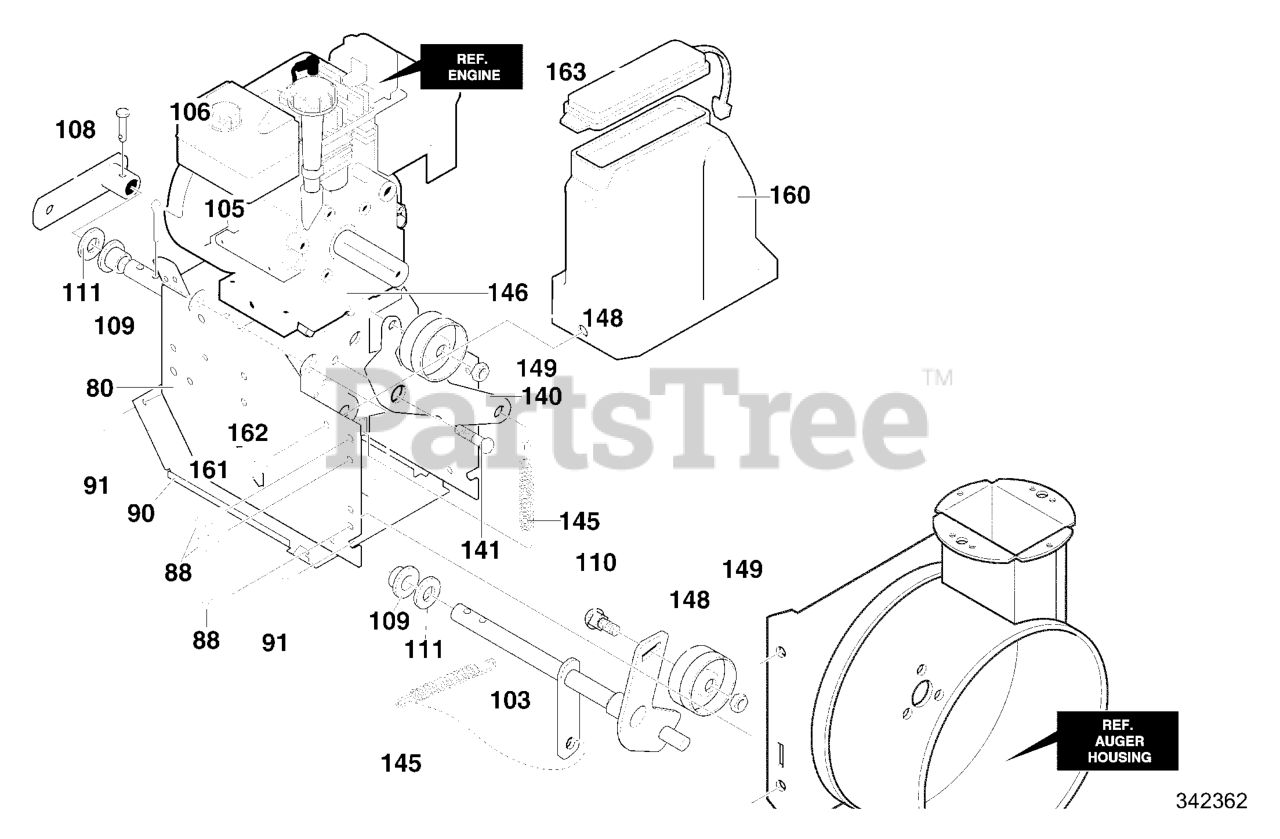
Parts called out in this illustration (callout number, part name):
80	FRAME ASSY
88	SCREW, 5/16-18 x 0.50
90	COVER, BOTTOM
91	SCREW, 1/4-20X .63
103	IDLER ASSEMBLY
105	PIN, HAIR .38DIAX1.64LG
106	PIN, KLIK 3/16" DIA
108	ASSY., SPRING ATTACH
109	BEARING, FL.
110	BOLT, 3/8-16X1.25 CARR.
111	WASHER, FLAT
140	LEVER, IDLER ARM TRACTION
141	BOLT, .625X.135 HHSH 5/16-18
145	IDLER SPRING TRACTION DRIVE
146	SCREW, 3/8-16 x 1.25
148	PULLEY, IDLER
149	NUT, 3/8-16
160	COVER, BELT
161	SCREW, 1/4-20X .63
162	WASHER, FLAT
163	LID, BELT COVER
